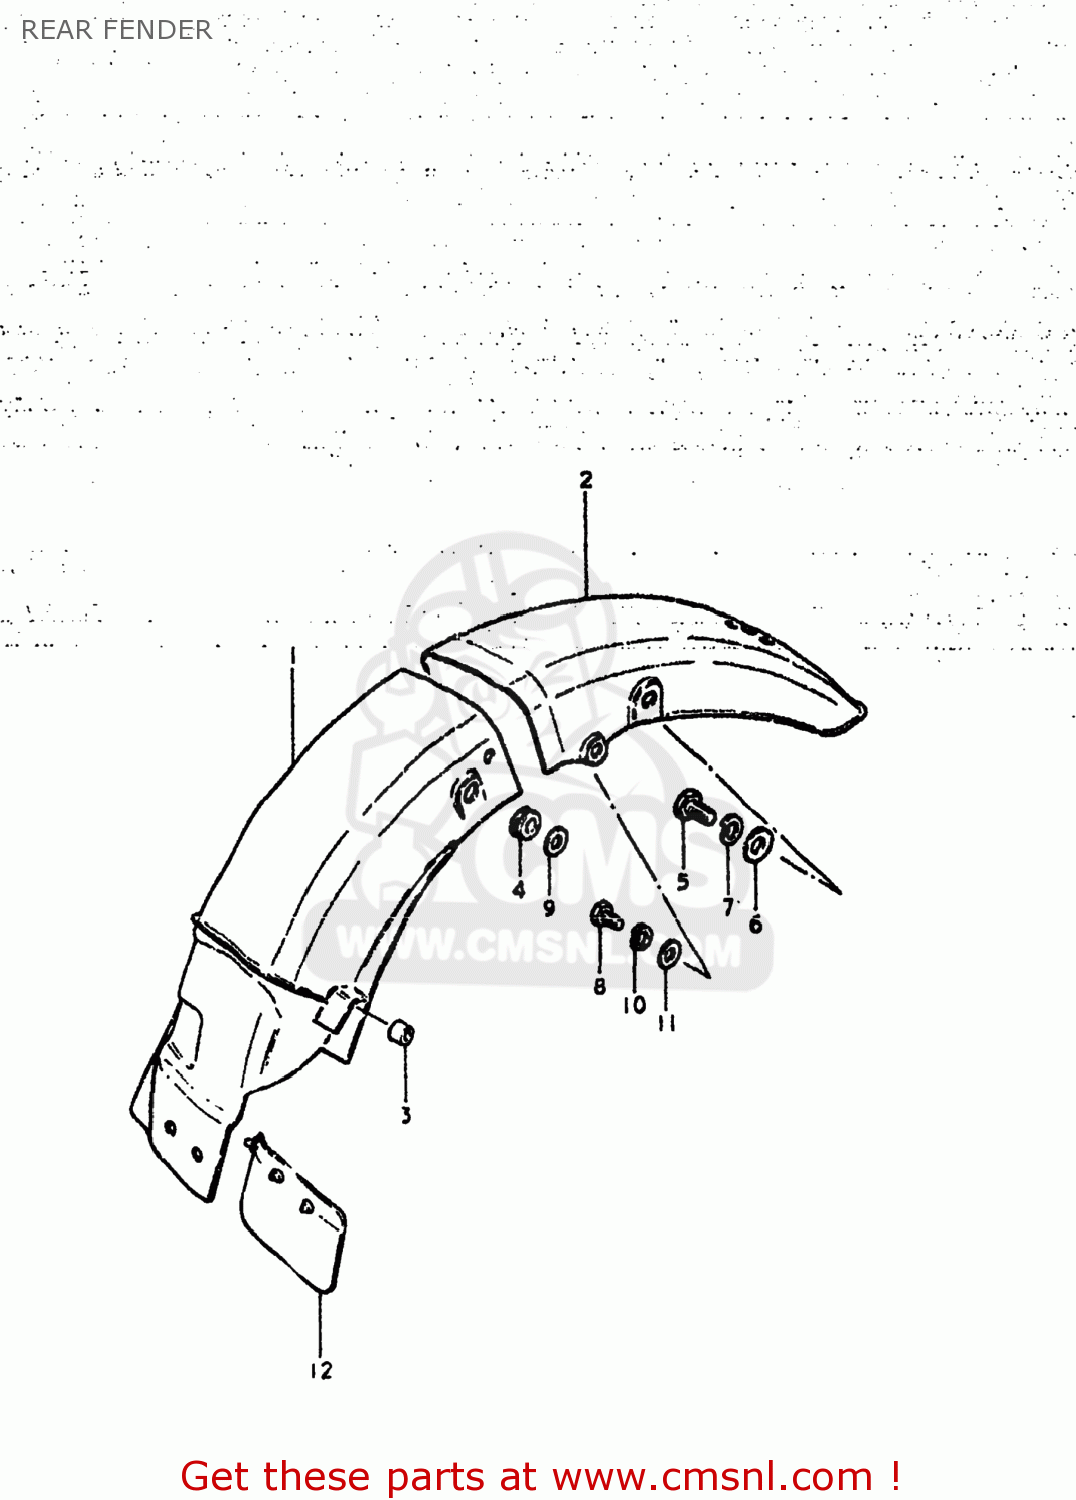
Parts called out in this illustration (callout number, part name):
1	FENDER,REAR
2	FENDER,REAR
3	CUSHION
4	CUSHION
5	BOLT
6	WASHER
7	LOCK WASHER
8	BOLT
9	WASHER
10	LOCK WASHER
11	WASHER 6MM
12	MUD GUARD,REAR FENDER
